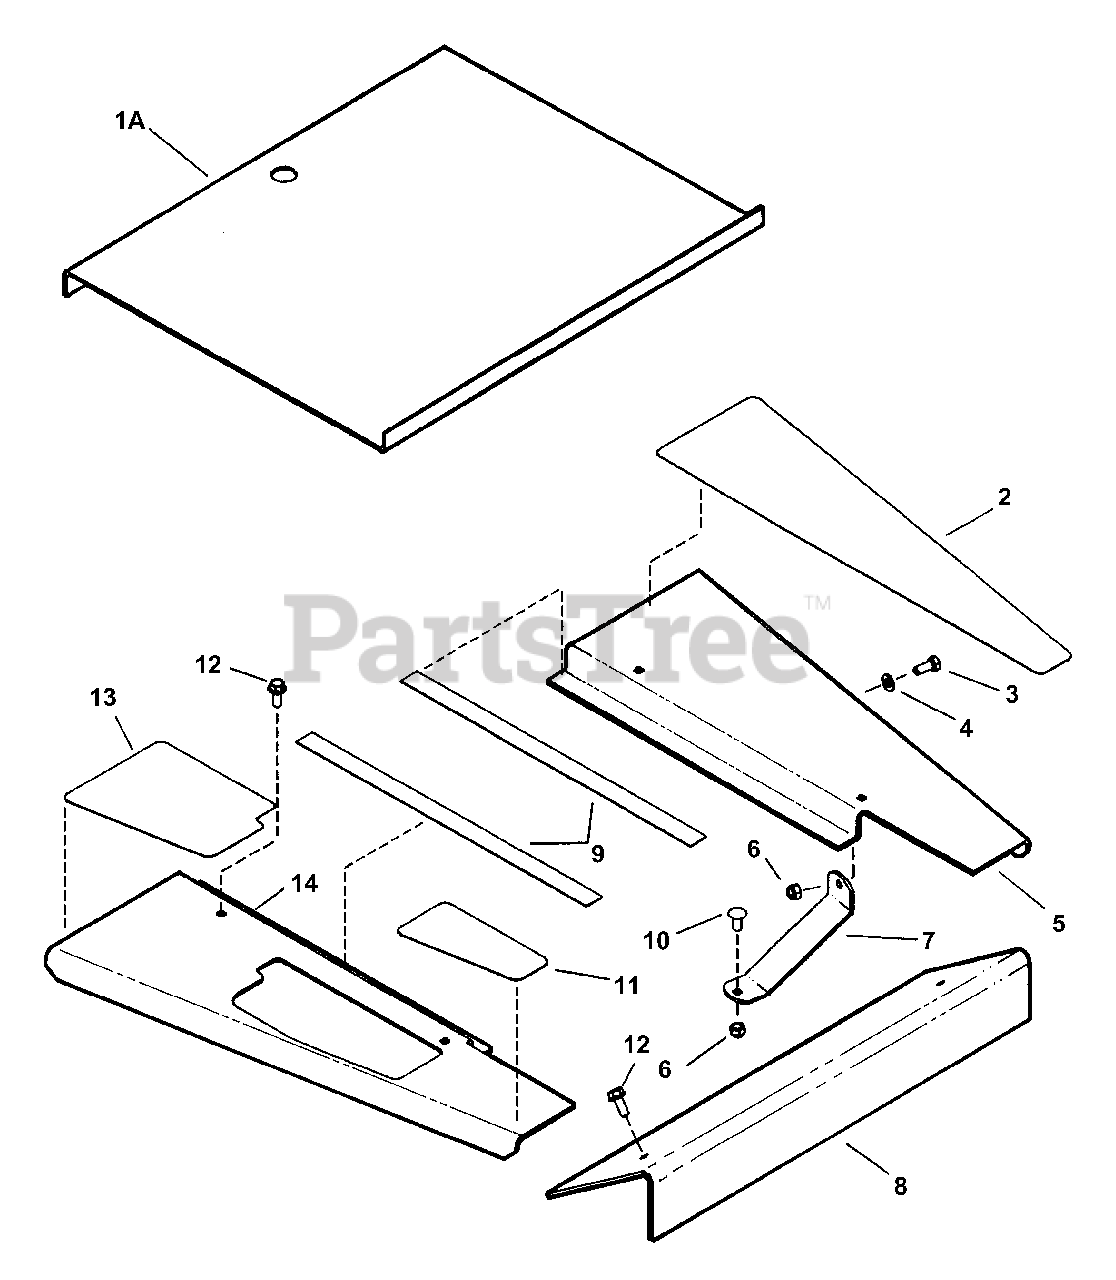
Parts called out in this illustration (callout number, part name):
1A	BRACKET, Floor Pan
2	PAD Left Hand Friction
3	BOLT, 5/16-18 X 3/4 GD5
4	WASHER, 11/32" Flat Lock
5	BRACKET, Left Hand Footrest
6	NUT, 5/16-18 HEX NYLON LOCK
7	BRACE, Left Hand Footrest
8	BRACKET, Footrest
9	PAD, Floor Pan Trim
10	BOLT, 5/16-18 x 3/4" Carriage Short Neck Grade 5
11	PAD, Right Hand Front Friction
12	SCREW, 5/16-18 x 3/4" Hex Self Tapping
13	PAD, Right Hand Rear Friction
14	BRACKET, Footrest (Right Hand)
